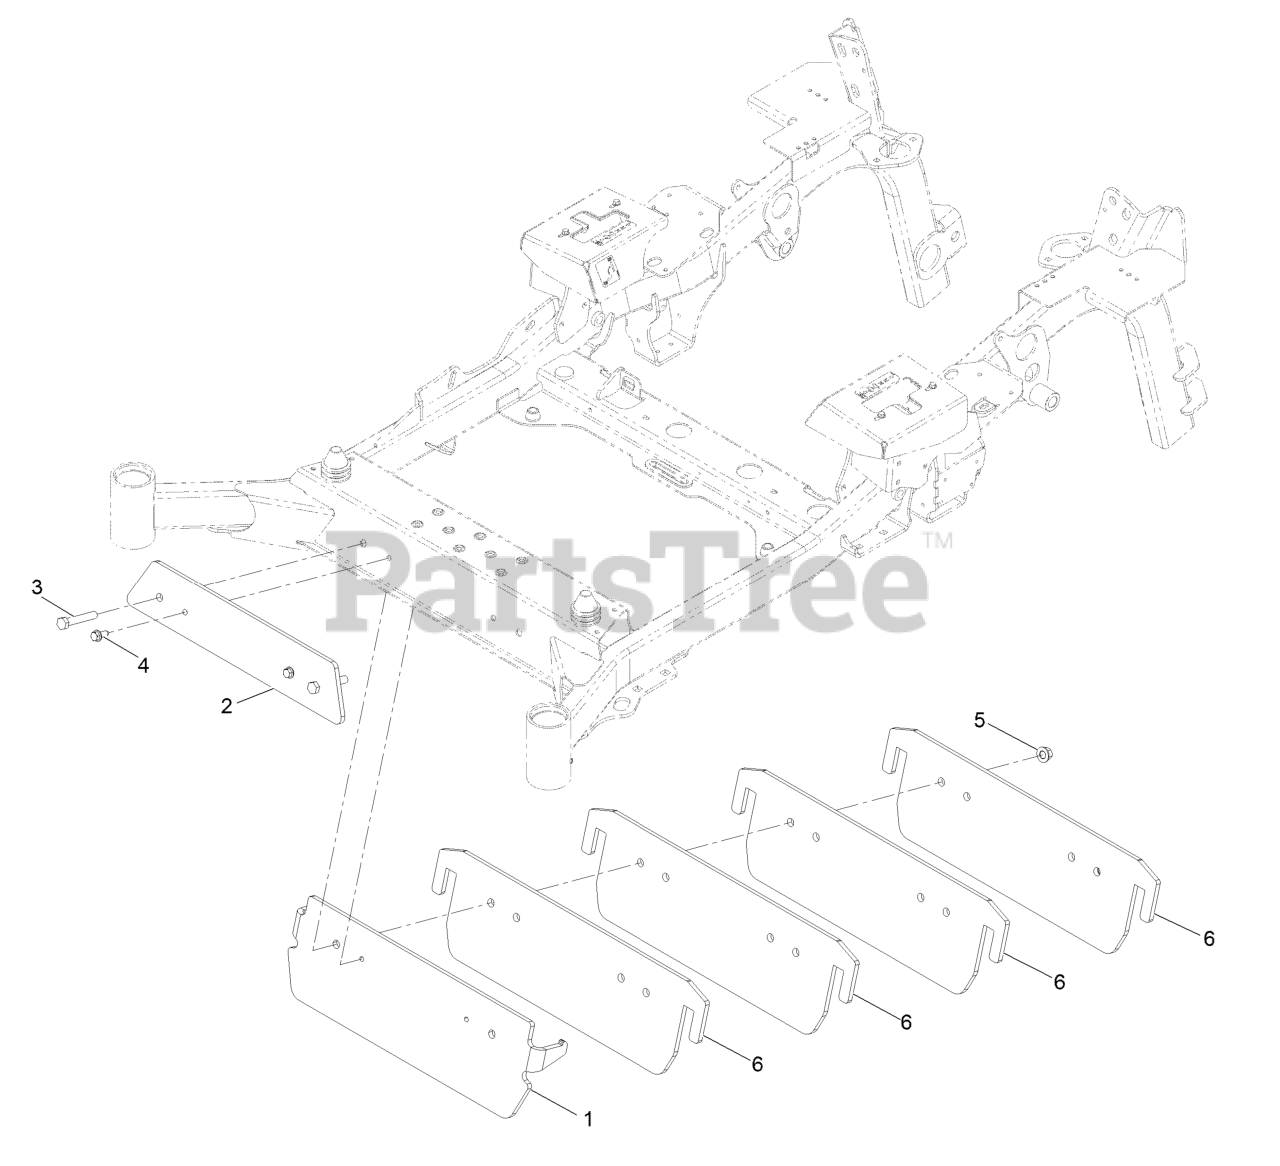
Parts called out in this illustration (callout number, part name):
1	Bracket-Weight
2	Weight-Outer
3	Screw-HH, TAP
4	Screw-Forming, Thread
5	Nut-Lock 1/2-13
6	Weight-Inner
